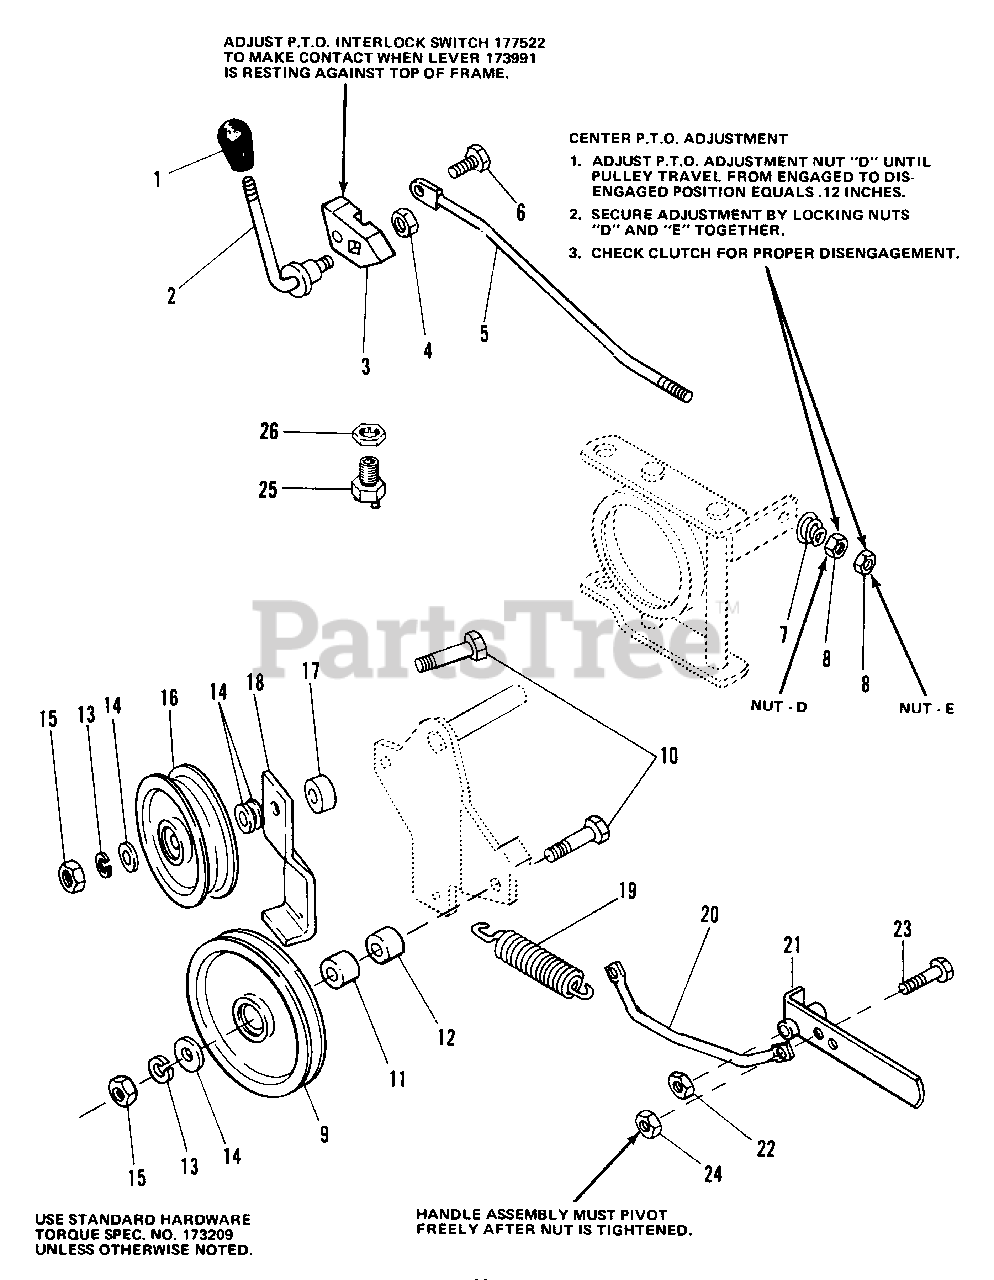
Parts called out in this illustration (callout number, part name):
1	KNOB
2	HANDLE, Clutch P.T.O.
4	LOCKNUT, Hex, 3/8-16
5	CONTROL ROD ASSEMBLY
6	CAPSCREW, Special
8	NUT, Hex, Full, 5/16-18
10	CAPSCREW, Hex Hd., 3/8-16 x 2
13	LOCKWASHER, 3/8
14	WASHER, 5/16
15	NUT, Hex, Full, 3/8-16
18	STOP, Belt
19	SPRING, Tension
20	ROD, Tension
21	HANDLE ASSEMBLY
22	LOCKNUT, Hex, 7/16-14
23	CAPSCREW, Hex Hd., 5/16-18 x 3/4
24	LOCKNUT, Hex, 5/16-18
25	SWITCH, Interlock
26	NUT, Pal
